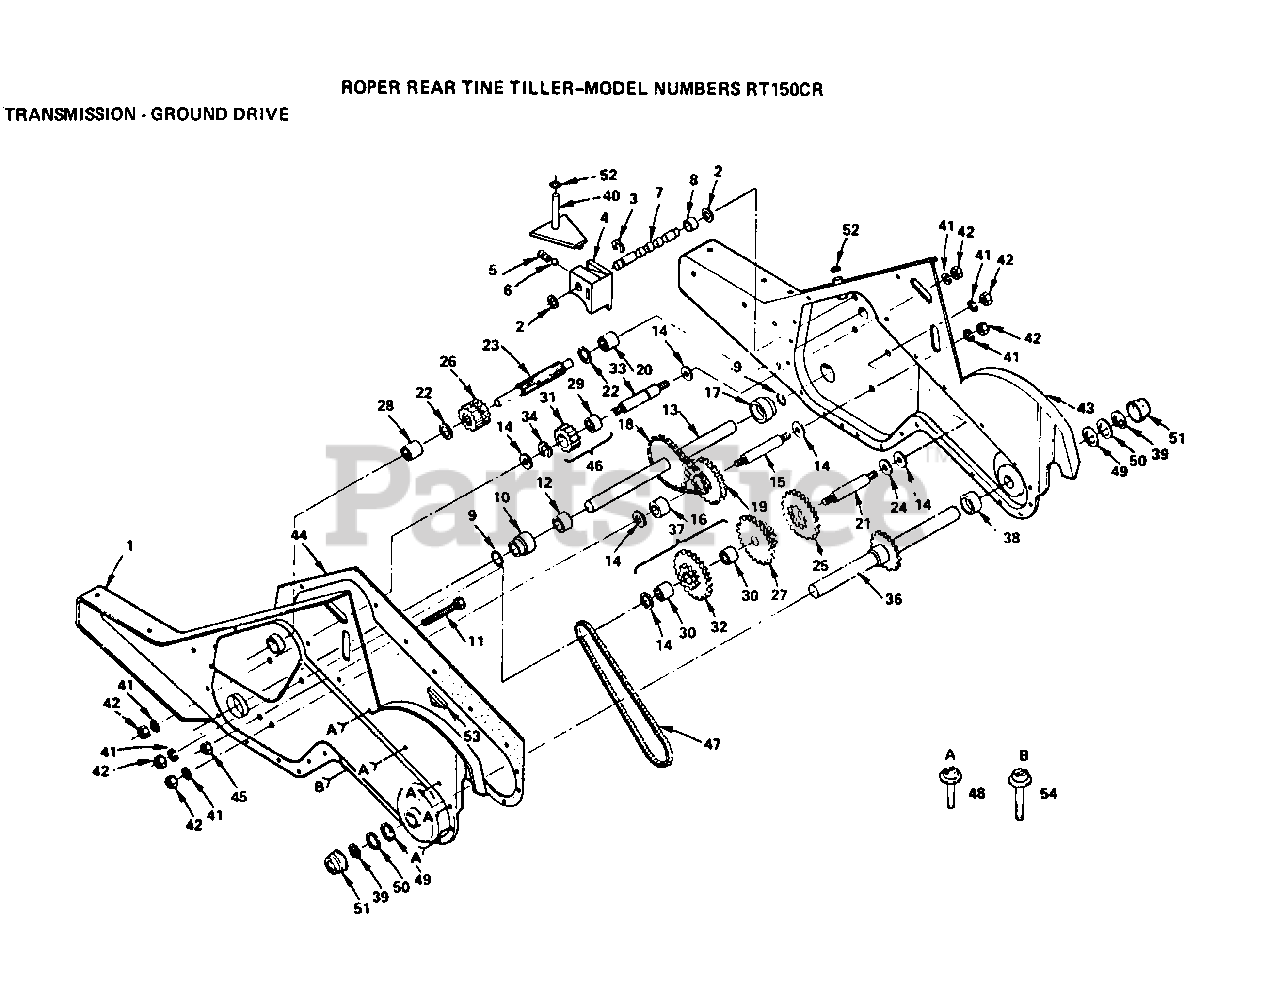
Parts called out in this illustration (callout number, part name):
2	WASHER SEAL CRT
3	KLIP RING
4	SHIFT FORK TI
5	SPRING-SHIFT CRT
7	SHAFT SHIFT CRT
8	SPACER SPLIT CRT
9	O RING CRT
10	"CRT, BEARING"
11	SCRW WHIZ LOK CRT
14	WASHER
15	SHFT 2ND RED. CRT
18	CHAIN CRT
19	SPRCKT 8 GEAR CRT
20	"TI, BEARING"
21	REDUCTION SHFT TI
22	"T, BEARING"
23	SHAFT-INPUT CRT
24	BRNG RACE
25	GEAR TI
26	PINION-INPUT CRT
27	GEAR TI
28	NEEDLE BRNG LT
29	NEEDLE BEARING TI
30	BEARING
31	GEAR-REV IDLR CRT
33	SHAFT CRT
34	KLIP RING
36	SHAFT ASSY TI
38	SPACER TI
39	RING SPIRAL CRT
40	ARM ASSY CRT
41	LOCKWASHER
42	NUT.ASF.HEX.7/16
44	GASKET TI
45	NUT.HEX.5/16-18
46	GEAR ASSY CRT
47	CHAIN.50 LINK TI
48	SCREW CRT
51	CUP.FORMED.
52	O-RING TI
